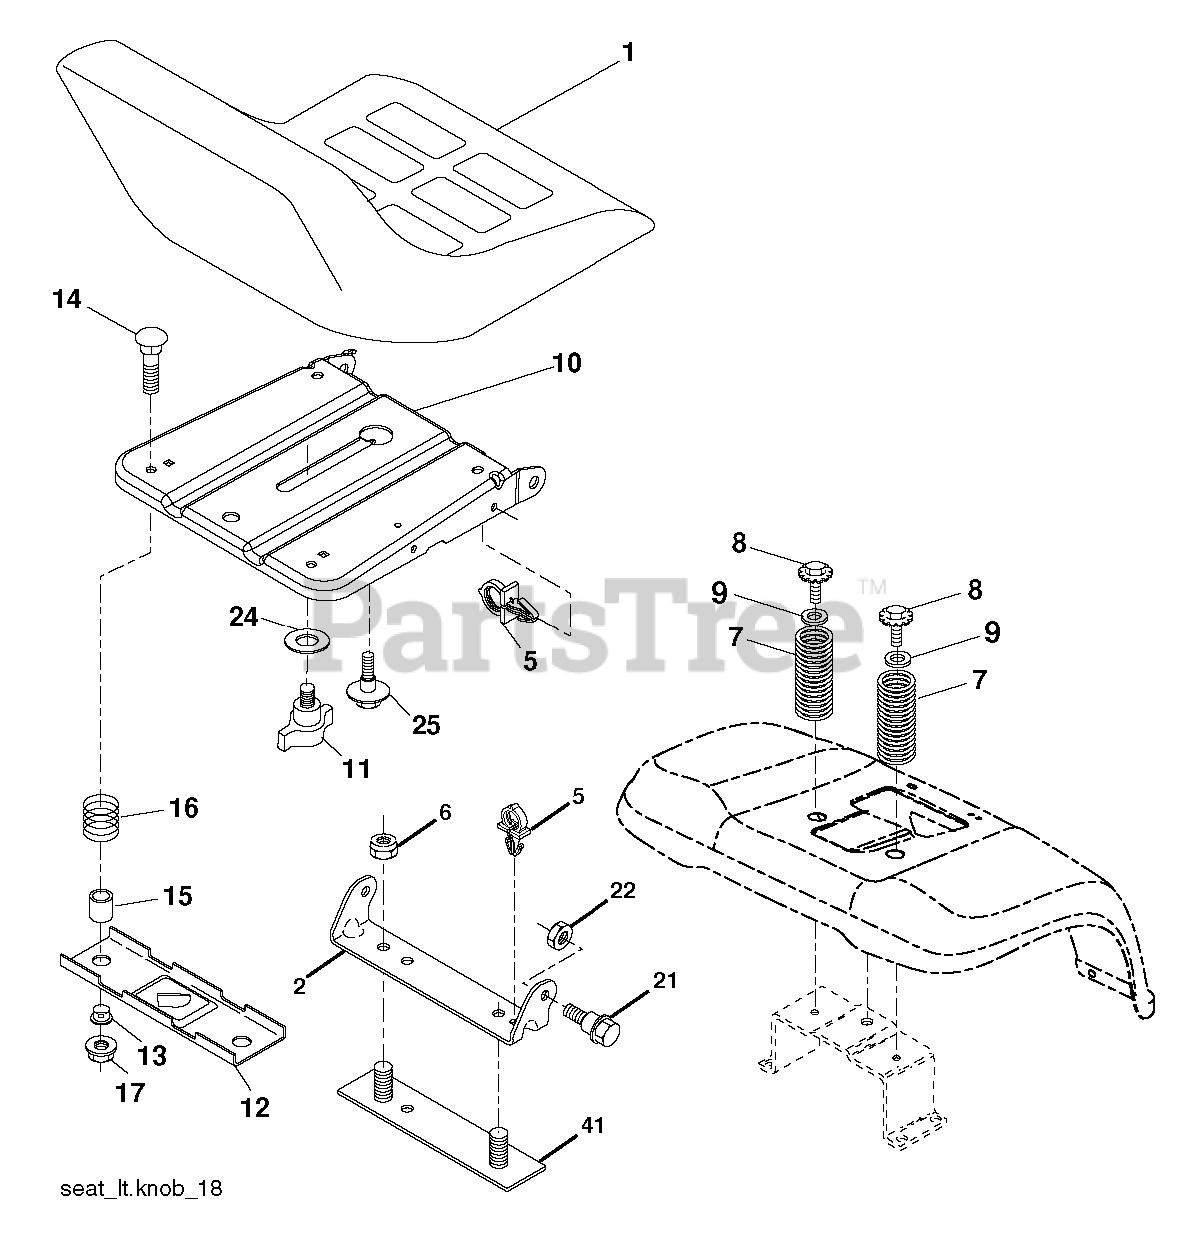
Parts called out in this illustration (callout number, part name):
1	RP SEAT
2	SEAT PIVOT BRKT
6	NUT
7	SPRING COMPRESSION
8	SCREW 3/8-16X1
9	WASHER
10	PAN.ASM.SEAT.1SLOT
11	KNOB.SEAT.ADJ.WINGNUT
12	BRKT.MNTNG.SWITCH.SEAT.BLACK
14	BOLT.ROUND.HEAD.SQUARE.NECK
15	SPACER SPLIT 28X.96
17	NUT T
21	BOLT.SHOULDER.5/16-18
22	NUT.71038.31-18.HEX.NYLOCK
25	BOLT,SHOULD
41	STRAP
